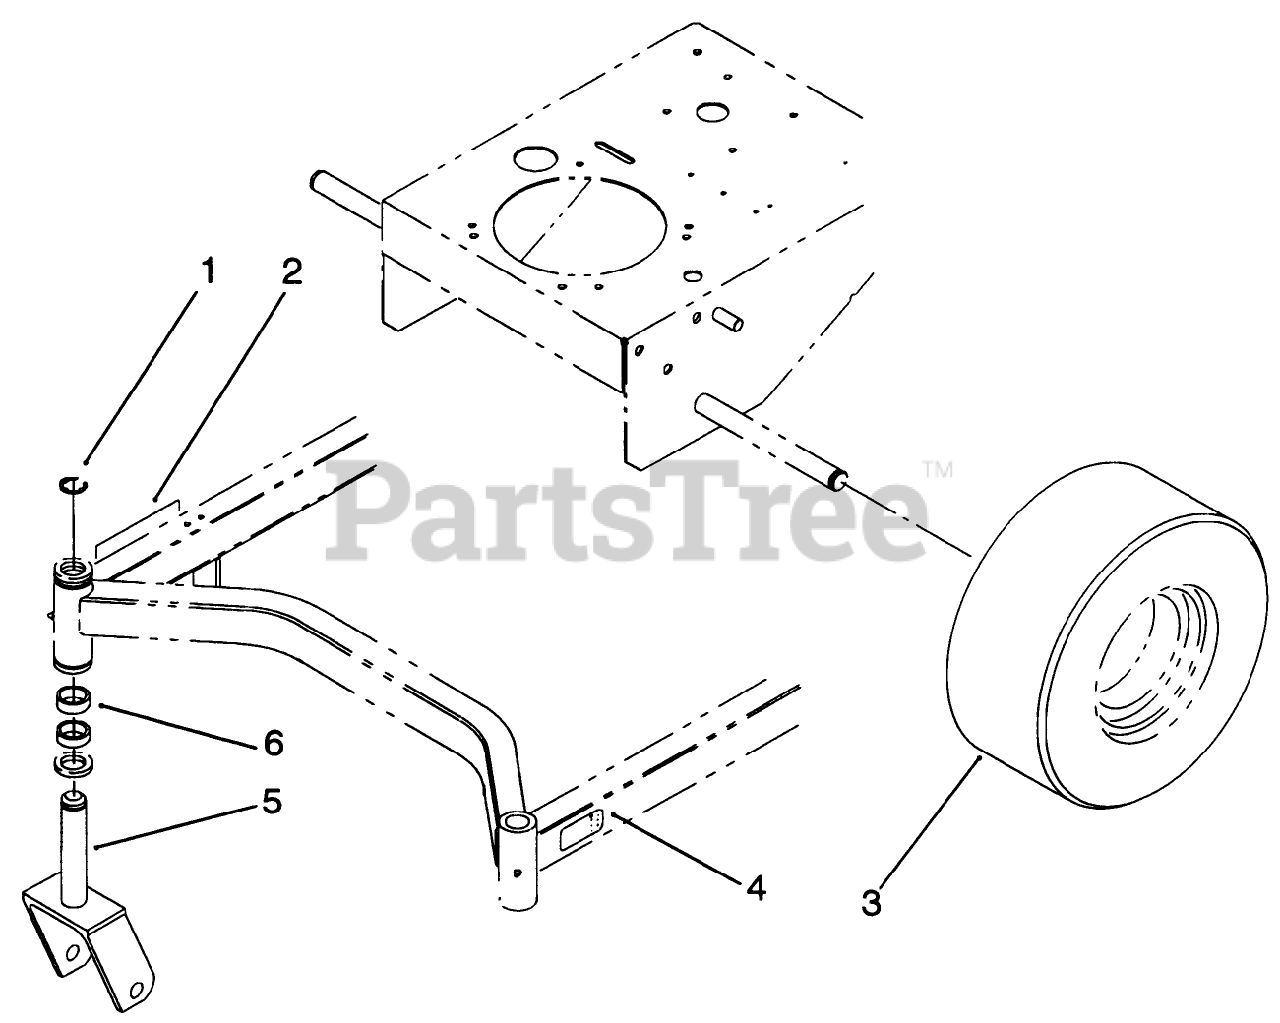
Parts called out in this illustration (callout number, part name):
1	RING-RETAINING
2	DECAL-HOC, RH
4	DECAL-HOC, LH
5	Fork
6	SPACER
